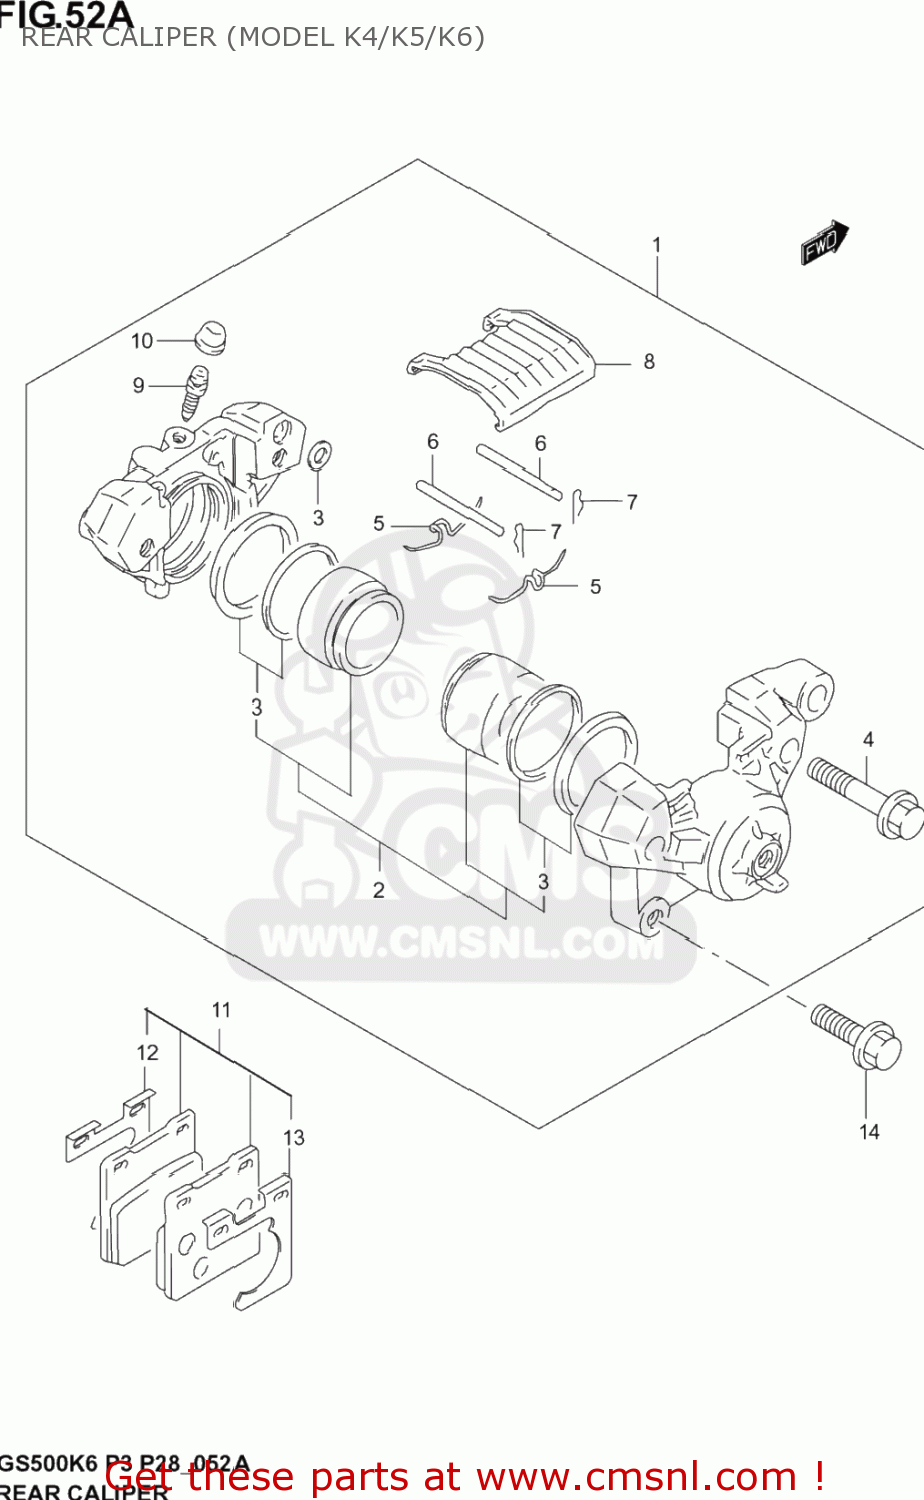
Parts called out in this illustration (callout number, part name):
1	CALIPER ASSY
2	PISTONSET
3	SEAL SET PIST.
4	BOLT
5	SPRING
6	PIN
7	CLIP
8	COVER
9	BLEEDER
10	CAP
11	PAD/SHIMSET
12	SIM PAD
13	SHIM, OUTER
14	BOLT
